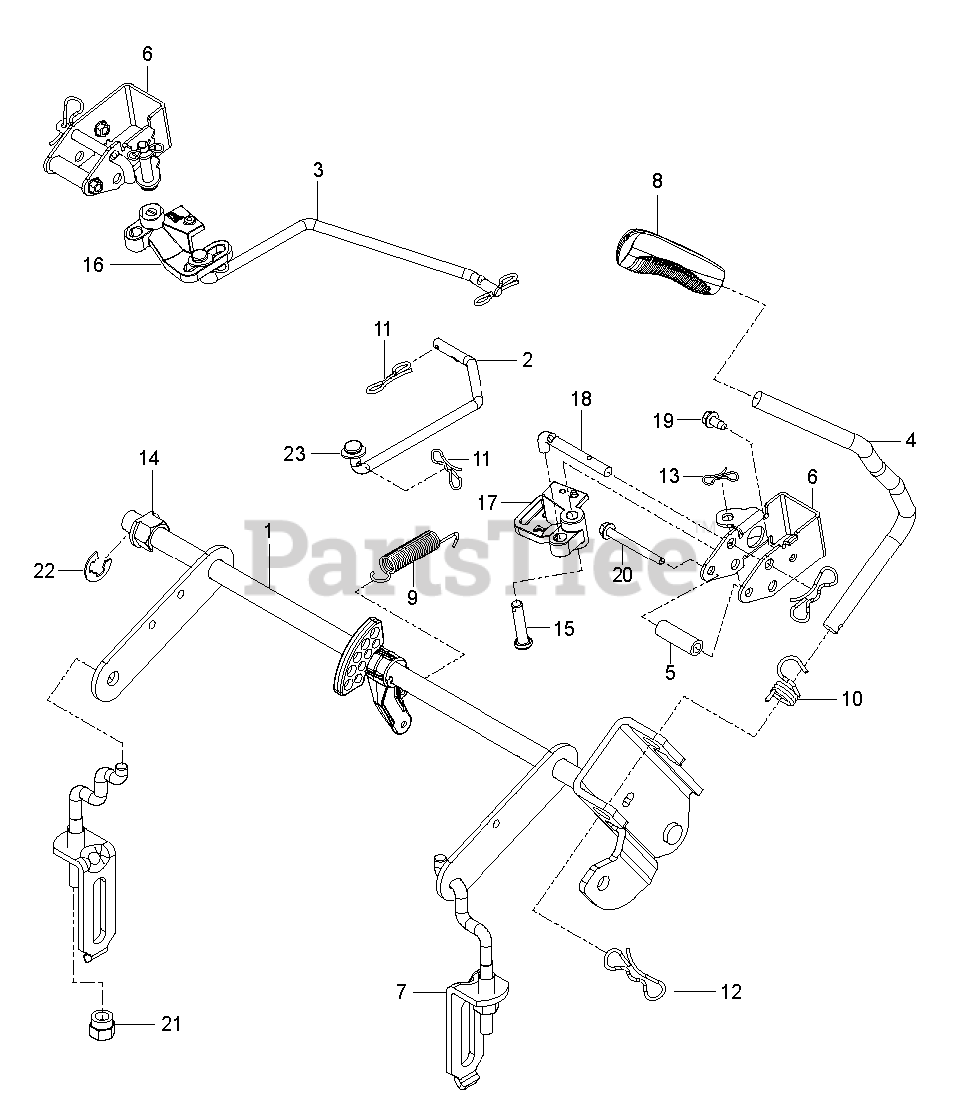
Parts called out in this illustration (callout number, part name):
1	SHAFT.ASM.RZ.DECK.LIFT.SRV
2	LINK.BRAKE.PARK.UPPER.LH
3	LINK.BRAKE.PARK.UPPER.RH
4	LIFT.LEVER.ASM.RZ.SERVICE
5	SPACER.334.ID.5.OD.1.5.L
6	BRACKET.BELLCRANK.PBRAKE X431
7	LINK.ASM.RZ.LIFT.SERVICE
8	GRIP.HANDLE.LIFT.PVC.428
9	RETURN.BRAKE.PARK.AUTO
10	SPRING.TORSION.LIFT.HANDLE
11	PIN COTTER;LOCKING;BOWTIE;1IN
12	PIN.COTTER.7/16.BOW TI.
13	PIN.COTTER.5/16.BOW TI
14	PLASTIC NUT
15	PIN.5.16X1.5
16	BELLCRANK.RH
17	BELLCRANK.LH
18	ROD.PUSH.BRAKE
19	SCREW.1/4-20X5/8
20	SCREW THD;ROLL;1/4-20 X 2.25
21	NUT, LIFT LINK 7/16-20
22	RETAINING RING LT
23	WASHER
